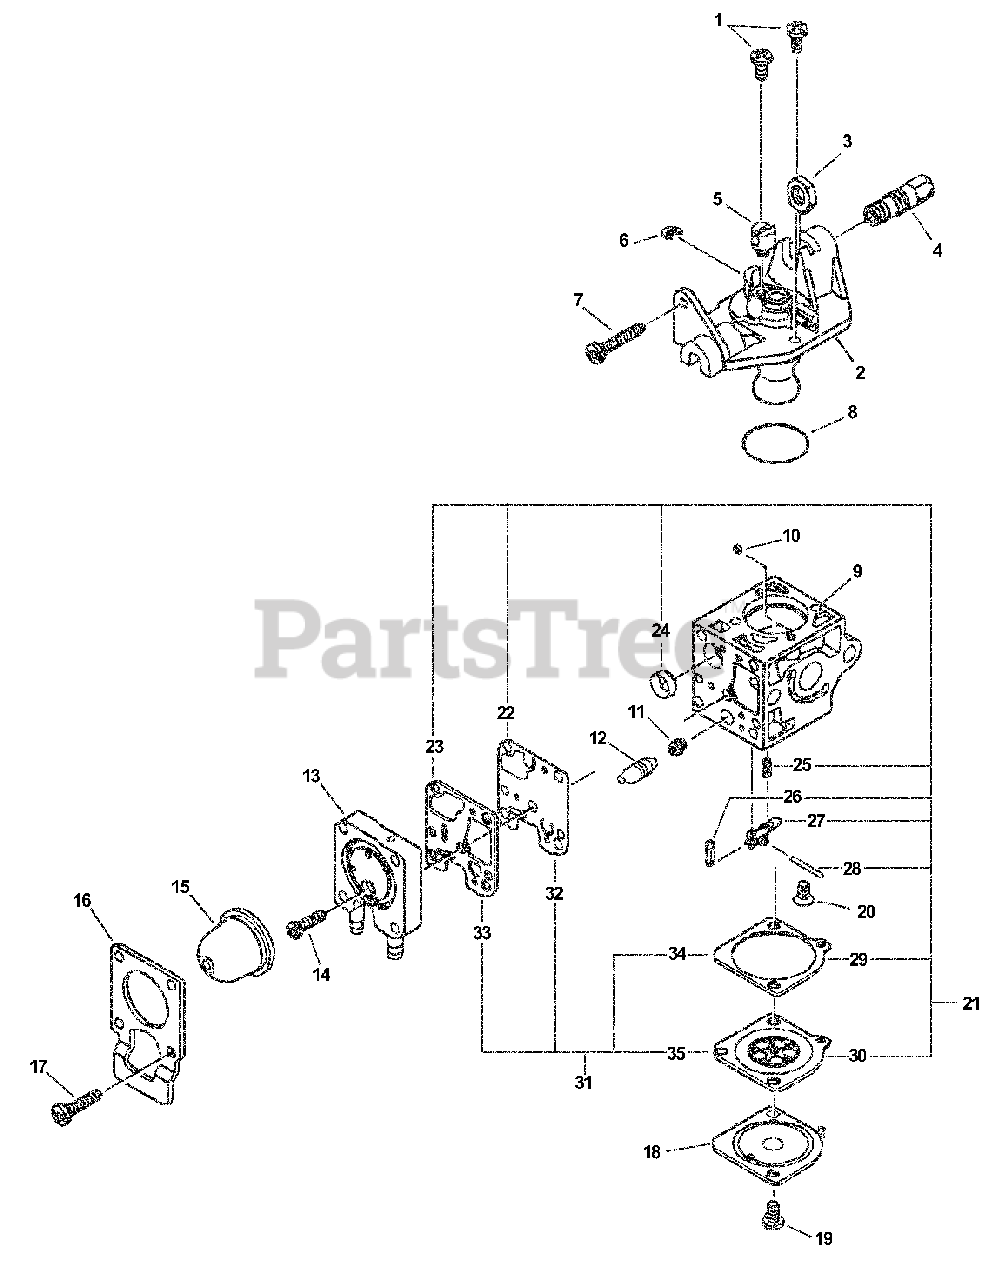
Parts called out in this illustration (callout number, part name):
2	ROTOR COVER ASSY
4	NUT, CABLE ADJUST
6	RING, RETAINING
7	SCREW, IDLE ADJUST
9	BODY, CARBURETOR
10	GUIDE, ROLLER
12	PLUG KIT
13	BASE, PURGE
14	SCREW, PURGE BASE
15	BULB, PURGE
16	RETAINER, PURGE BULB
17	SCREW, RETAINER
18	COVER, METERING
20	SCREW, METERING LEVER PIN
21	REPAIR KIT
22	DIAPHRAGM, PUMP
23	GASKET, PUMP
24	STRAINER
25	SPRING, METERING LEVER
26	VALVE, INLET NEEDLE
27	PIN, METERING LEVER
28	LEVER, METERING
29	GASKET, METERING
30	DIAPHRAGM, METERING
31	DIAPHRAGM/GASKET KIT
32	DIAPHRAGM, PUMP
33	GASKET, PUMP
34	GASKET, METERING
35	DIAPHRAGM, METERING
